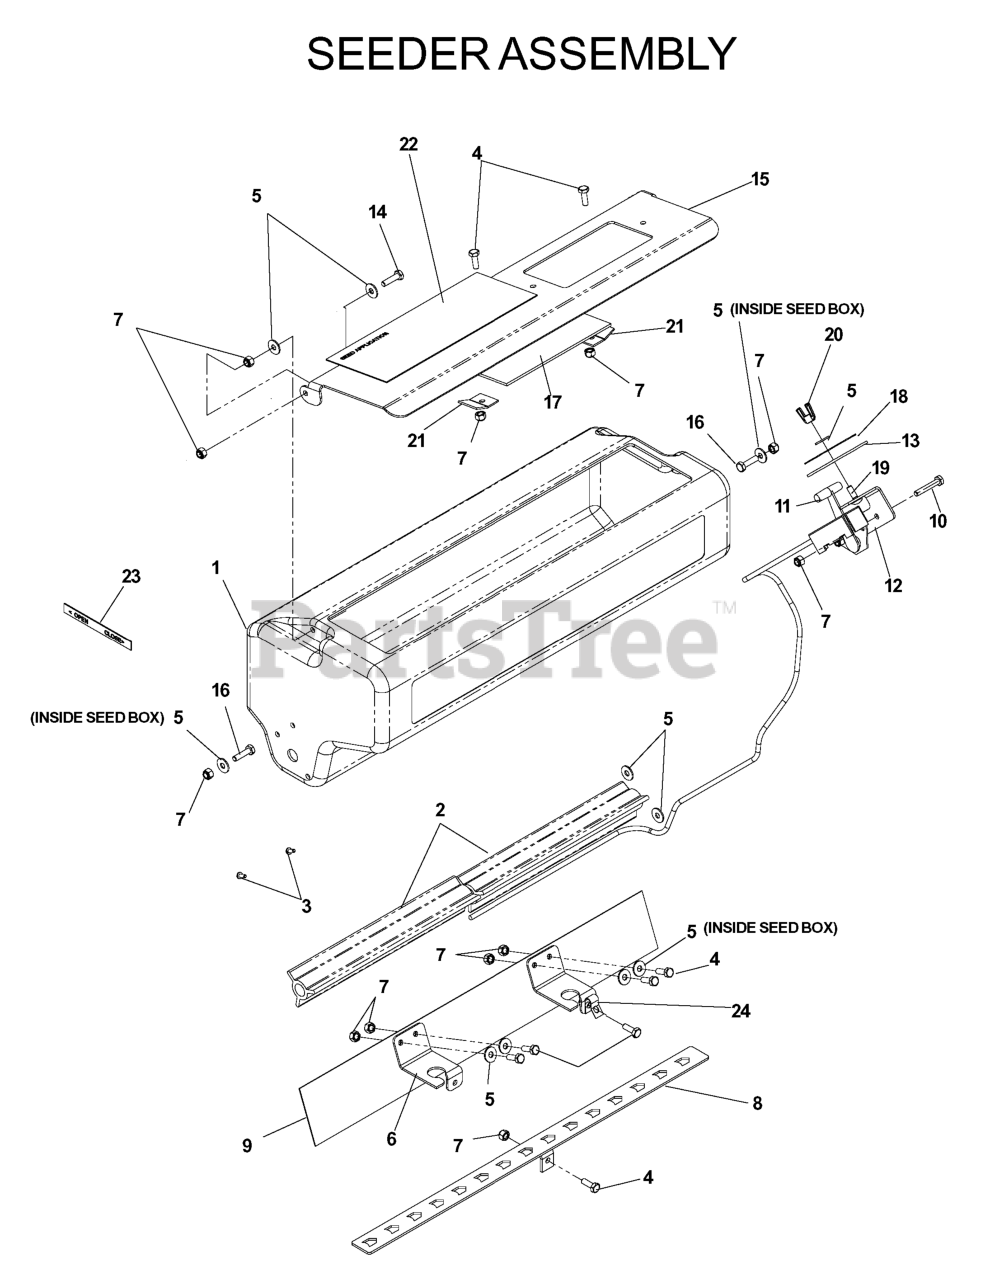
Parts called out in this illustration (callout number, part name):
1	SEEDBOX
3	R/B 108495 SCR SLF TP 8-32X3/8
4	HCS 1/4C X 3/4 HCS
5	WASHER 1/4 FLAT
7	NUT.1/4-20.HEX.NYLOC.ZD
9	R/B 109375 SHIELD
10	SCW 1/4-20 X 1-1/2 HEX
11	CONTROL, PUSH/PULL ASSEMBLY
14	HCS 1/4C X 1
15	SEED DOOR ORANGE
16	HCS 1/4 X 1
17	SEED WINDOW
18	DECAL, SEED DIAL
19	R/B 990316 BLT CRGE5/16-18X3/4
20	WING NUT 1/4
21	WINDOW CLIP
22	DECAL, SEED APPL
23	DECAL, OPEN/CLOSE
24	BRACKET, PUSH/PULL
540053411	RETAINING RING
